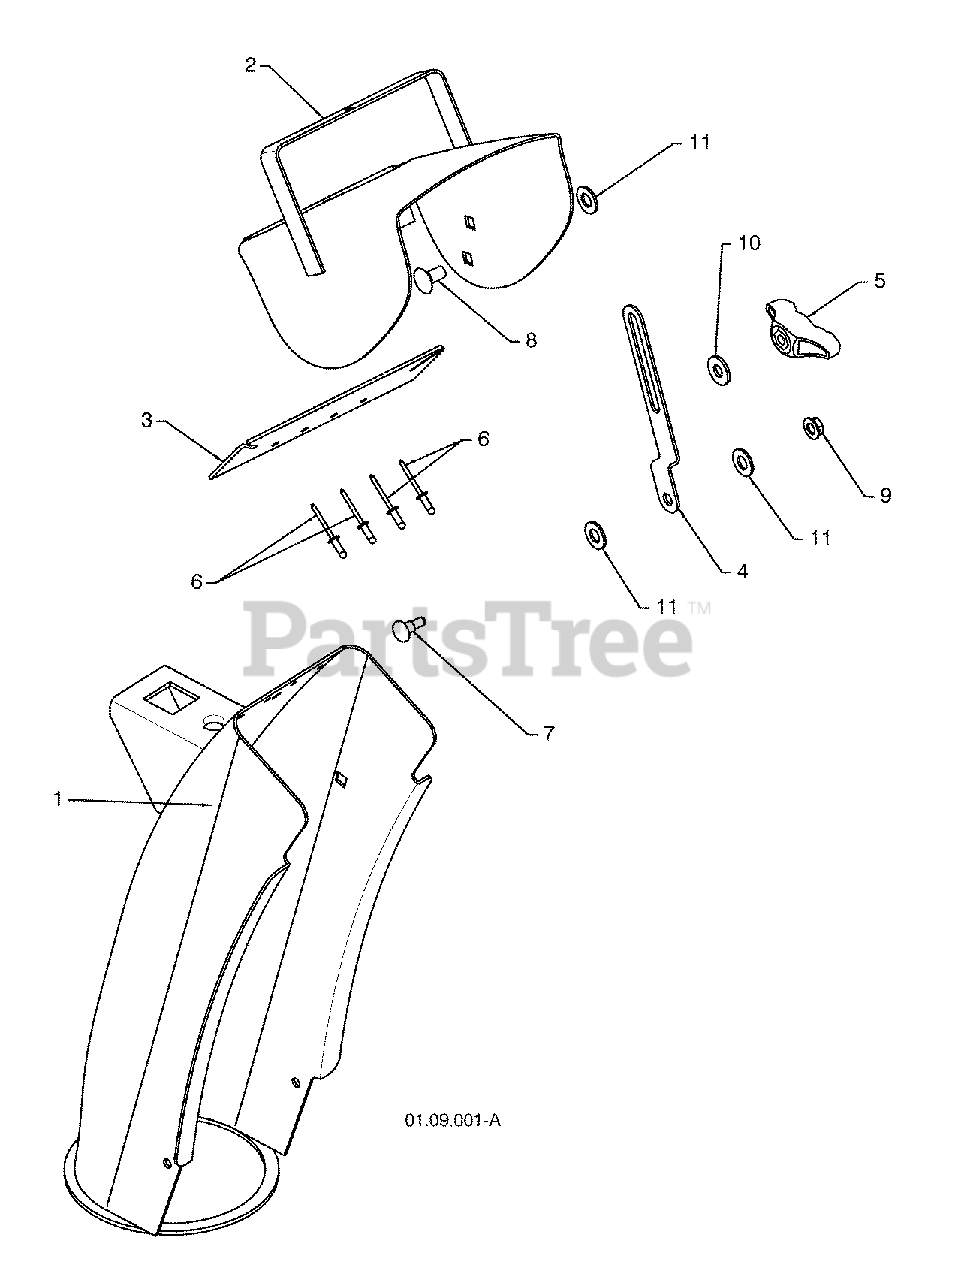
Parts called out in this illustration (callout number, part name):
1	CHUTE WELDMENT
2	DEFLECTOR WELDMENT
3	DEFLECTOR SEAL
4	STRAP
5	KNOB BLACK
7	SHOULDER BOLT 1/4--20 X .704
8	CARRIAGE BOLT 5/16--18 X .625
9	NUT 1/4--20
11	PLASTIC WASHER
